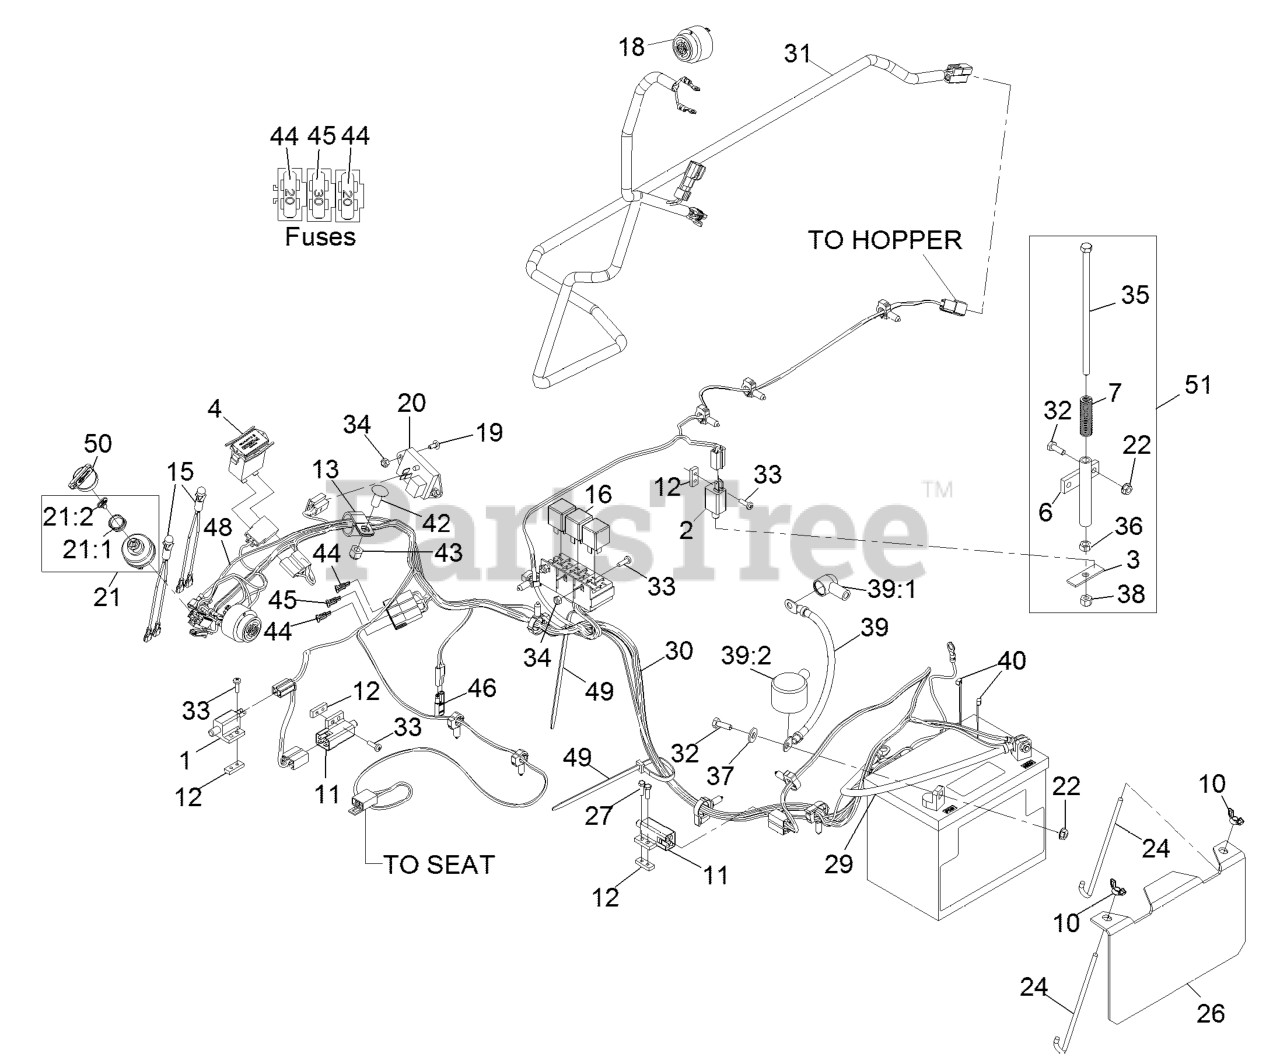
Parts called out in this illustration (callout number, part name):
1	SWITCH-OPEN, NORMALLY
2	SWITCH-CLOSED, NORMALLY
3	PLATE-SWITCH, SEAT
4	METER-HOUR
6	MOUNT-SPRING, SEAT
7	SPRING-SWITCH, SEAT
10	WINGNUT
12	PLATE-TAPPED
13	CLIP-LOOM
15	INDICATOR-LED, RED
18	ALARM-TONE, DUAL
19	BOLT-CARR
20	MODULE-DELAY, SEAT
21	ASM,SWITCH W/NUT
21:1	NUT-SWITCH, IGNITION
21:2	KEYS-IGNITION (SPARE PAIR
24	BOLT-HOLDDOWN
26	HOLD DOWN-BATTERY
29	CABLE-BATTERY, NEGATIVE
30	HARNESS-WIRING NAVIGATOR
31	HARNESS-WIRE, HOPPER
32	SCREW-HH
33	SCREW-PPH
34	NUT-LOCK, NI
35	SCREW-HH
36	NUT-HEX
37	WASHER-FLAT
38	NUT-LOCK, NI
39	CABLE-BATTERY, POSITIVE
39:1	INSULATOR-SOLENOID
39:2	INSULATOR-BATTERY
40	TIE-CABLE
42	SCREW-CARR
43	NUT-LOCK, NI
44	FUSE-BLADE TYPE, 20 AMP
45	FUSE-BLADE TYPE, 30 AMP
46	CAP-PLUG
48	HARNESS-LIGHT INDICATOR (
49	TIE-PLASTIC
50	KEY-IGNITION
51	HOPPER SWITCH ACTUATOR AS
